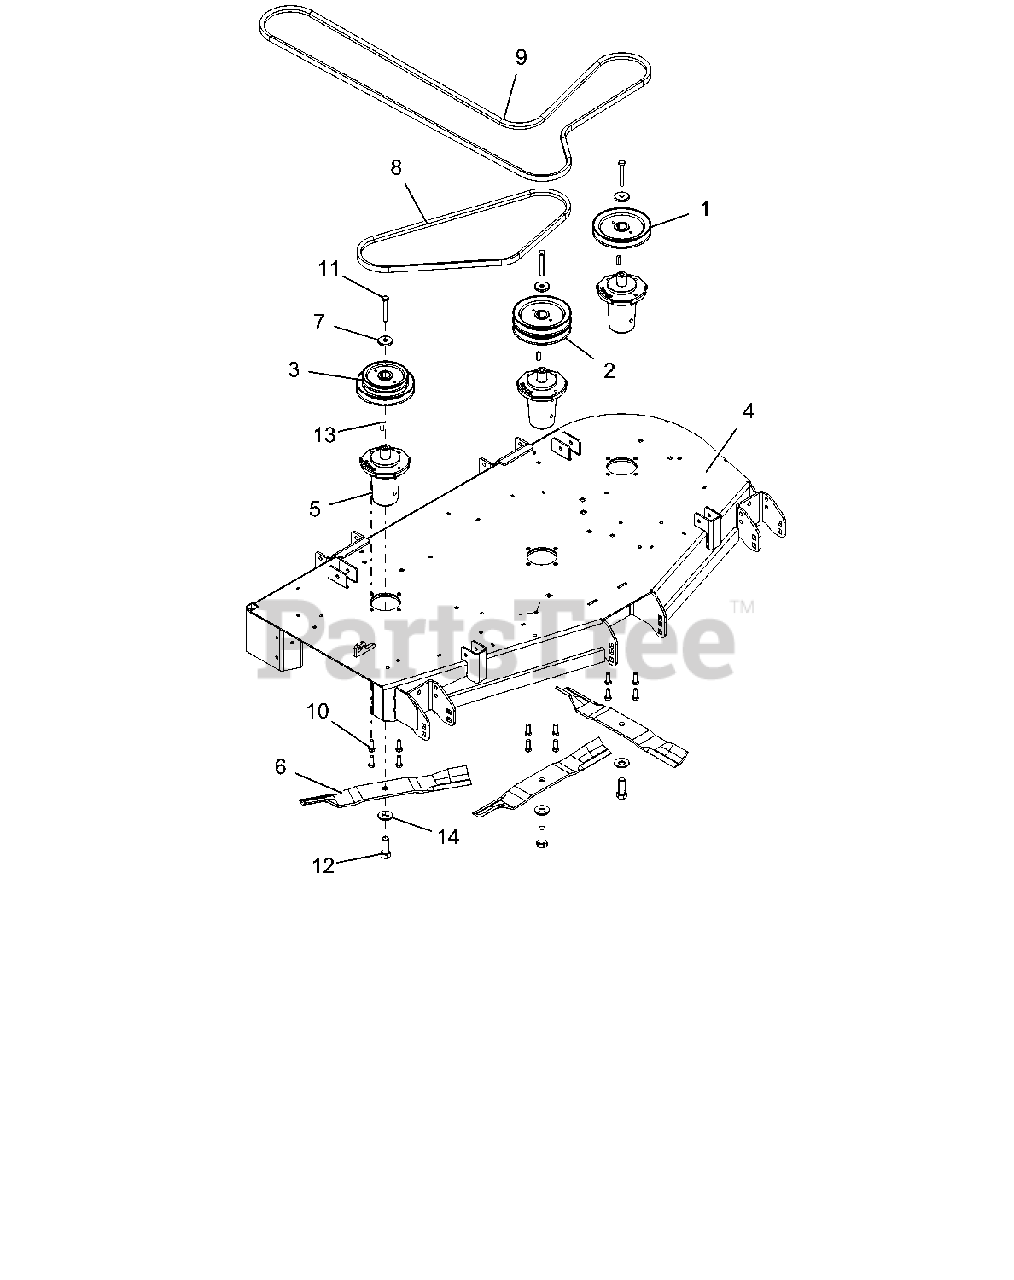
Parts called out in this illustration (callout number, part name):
1	PULLEY, SINGLE-1"ID X 6" OD
2	PULLEY, DOUBLE
3	PULLEY, DBL-1"IDX6.00"&4.75"OD
4	52"SIDE DISCH DECK WMT W/SAFE
5	ASM, MAINT FREE SPINDLE
6	BLADE, 18.00" MOWER (HI-LIFT)
7	RETAINER, SHEAVE
8	V-BELT, B-COGGED
9	V-BELT, HB RAW EDGE EPDM
10	BLT-HEX .38-16X1.0 GR8 YZ EP30
11	BLT-HEX .38-16X2.75 GR8 YWZC
12	BLT-HEX .62-18X1.75 GR8 YWZC
13	KEY, SQ .25X.25X1.00 RC 40-50
14	WSHR-BLVL .669X1.535X.138
